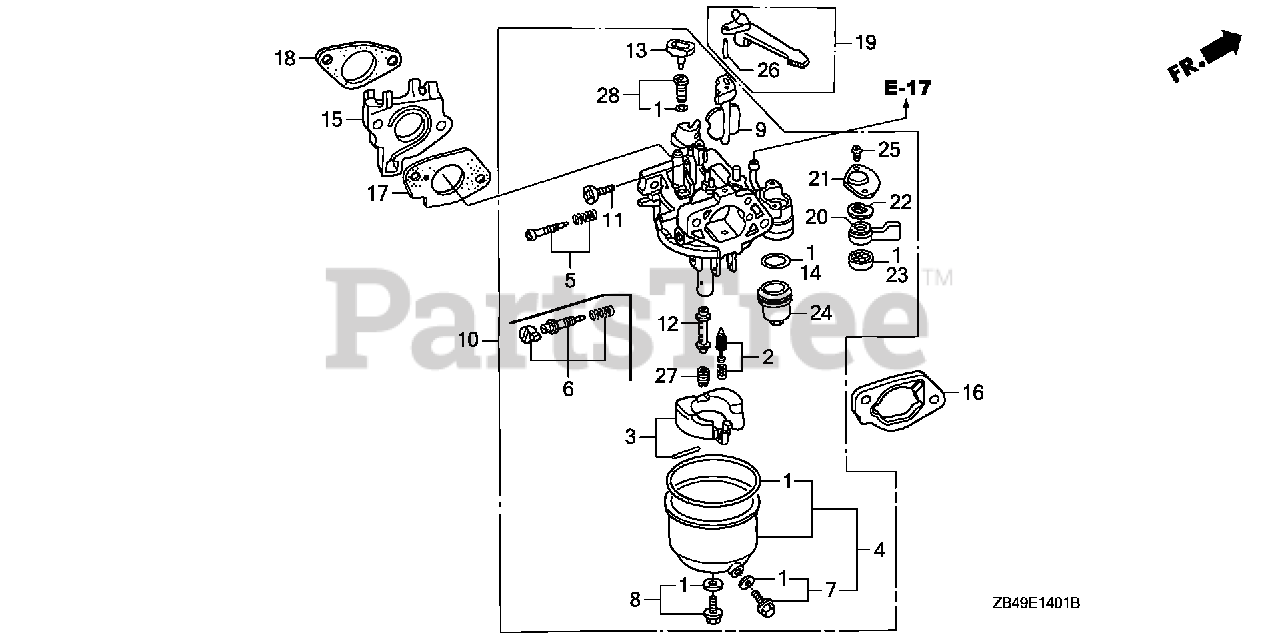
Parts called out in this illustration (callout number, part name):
1	GASKET SET (INCLUDES 16173-001-004)
2	VALVE SET, FLOAT
4	CHAMBER SET, FLOAT
6	SCREW SET, PILOT
7	SCREW SET, DRAIN
8	SCREW SET
10	CARBURETOR ASSY. (BE70E B)
11	SCREW, THROTTLE STOP
12	NOZZLE, MAIN
13	COLLAR, SETTING
14	GASKET, FUEL STRAINER CUP
15	INSULATOR, CARBURETOR
16	SPACER, CARBURETOR
17	GASKET, CARBURETOR
18	GASKET, INSULATOR
19	LEVER, CHOKE (STD)
20	LEVER, PETCOCK
21	PLATE, LEVER SETTING
22	SPRING, PETCOCK LEVER
23	GASKET, PETCOCK
24	CUP, FUEL STRAINER
25	SCREW, PAN (3X6)
26	PIN, SPRING (2X12)
27	JET, MAIN (#82)
27	JET, MAIN (#85)
27	JET, MAIN (#88)
28	JET SET, PILOT (#40)
